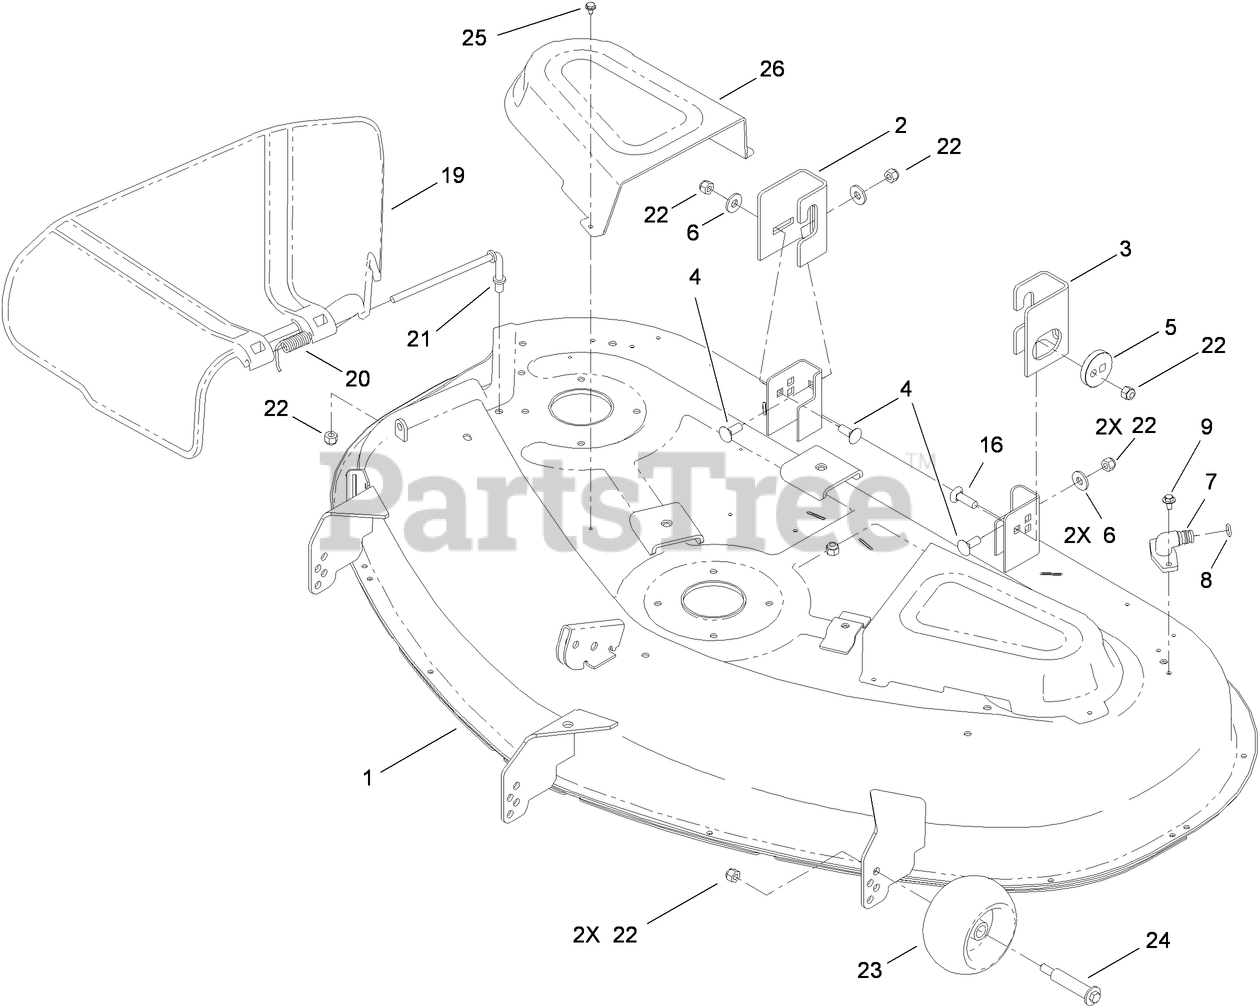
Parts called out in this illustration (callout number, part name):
2	BRACKET-HANGER, RIGHT REAR
3	BRACKET-HANGER, LEFT REAR
4	BOLT-CARR
5	ECCENTRIC
6	WASHER-HARDENED
8	O-RING
9	SCREW-HHFTF
16	SCREW-CARR
19	DEFLECTOR
20	SPRING-TORSION
21	ROD-PIVOT
22	NUT-LOCK, NI
23	ROLLER-SCALP, ANTI
24	BOLT-SHOULDER
25	SCREW-HWHTF
26	COVER-BELT
